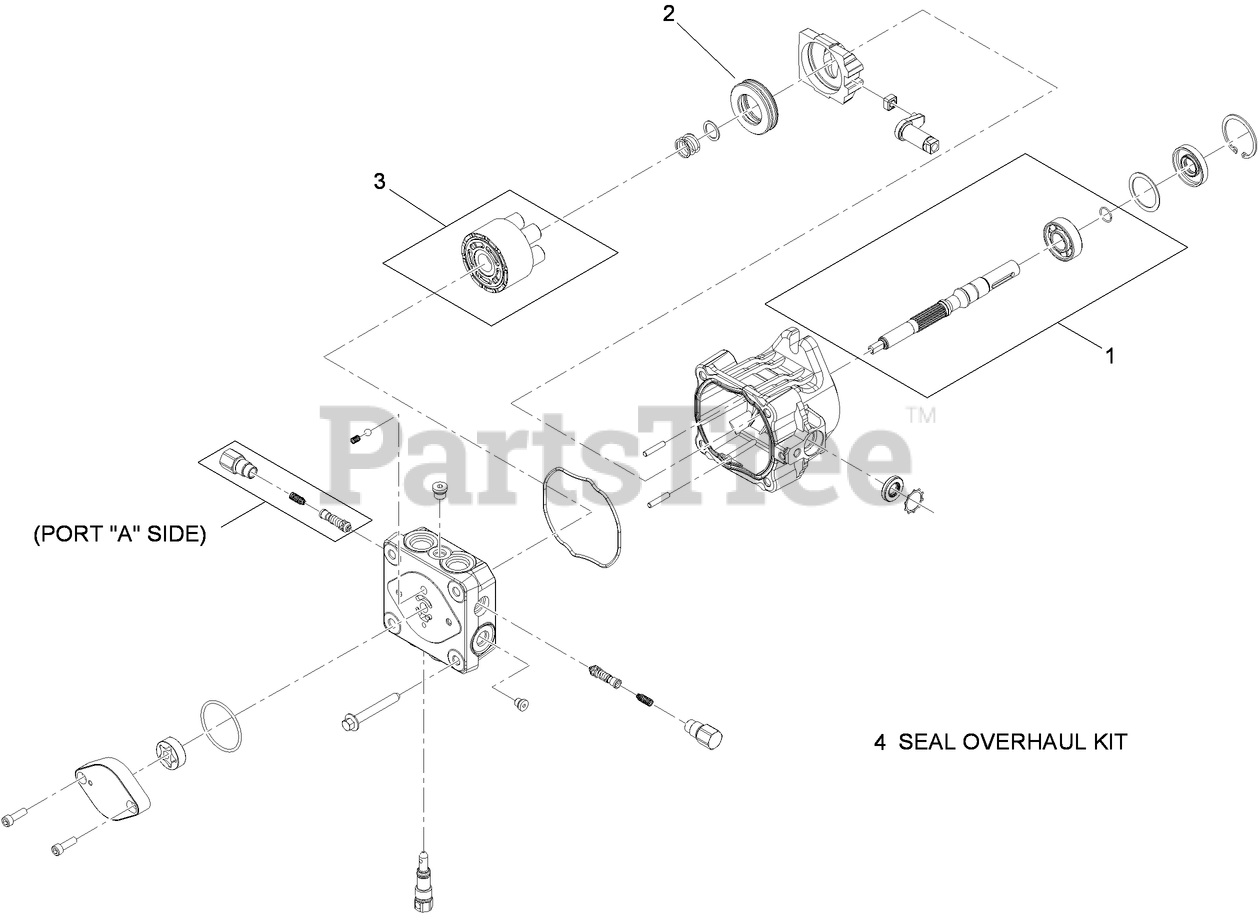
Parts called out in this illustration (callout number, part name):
1	INPUT SHAFT KIT
2	BEARING-THRUST
3	CYLINDER BLOCK KIT
4	SEAL OVERHAUL KIT
